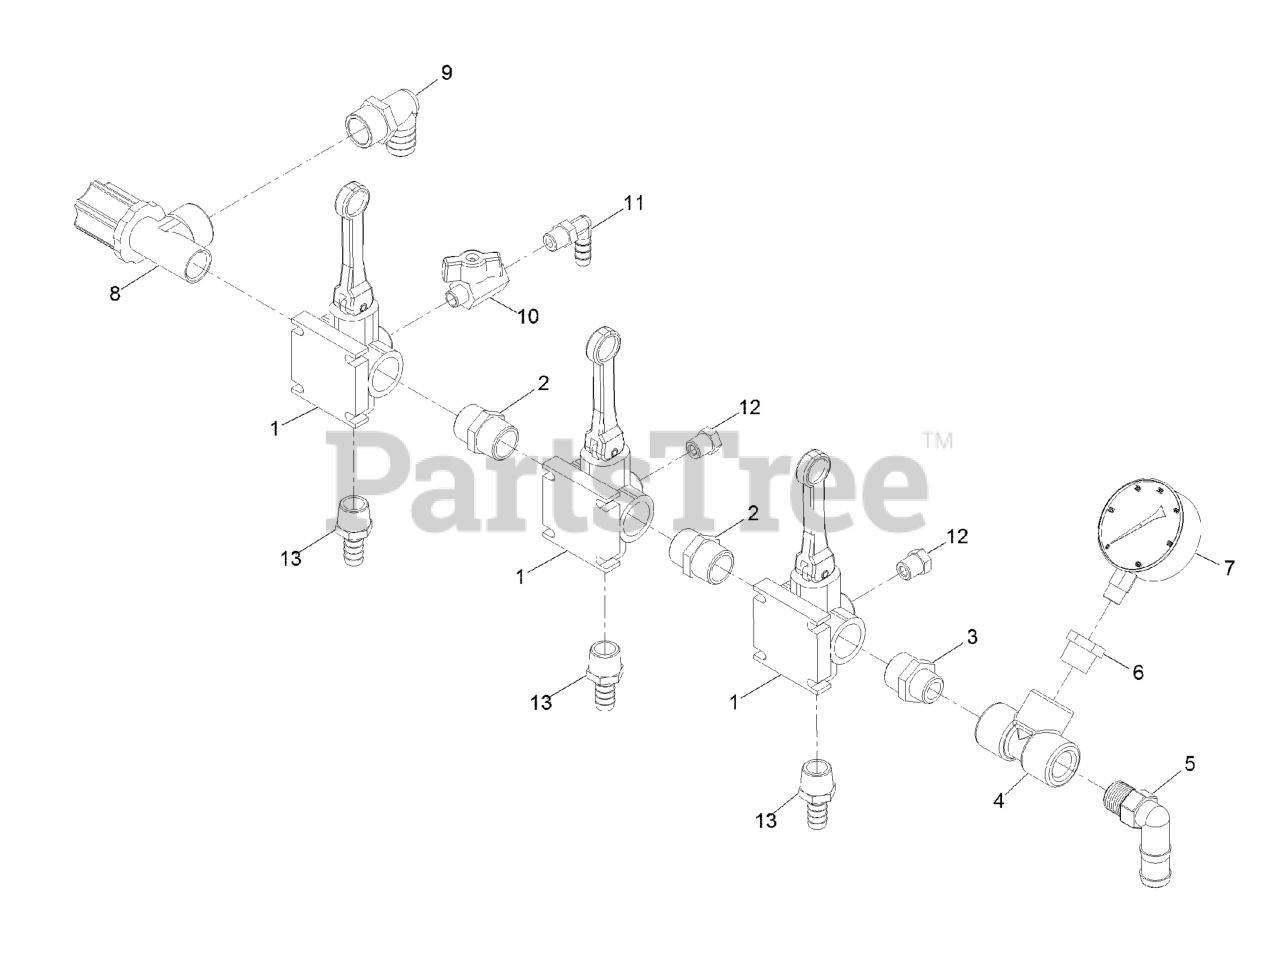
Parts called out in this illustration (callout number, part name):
1	VALVE-DIRECTO
2	FITTING-NIPPLE
3	FITTING-NIPPLE
5	ELBOW-90
6	FITTING-REDUCER
7	GAUGE
8	VALVE-THROTTLE
9	FITTING-ELBOW, 90
10	VALVE-CHROME, 1/4
11	FITTING-ELBOW, 90
12	PLUG-VALVE
13	FITTING-HOSEBARB
